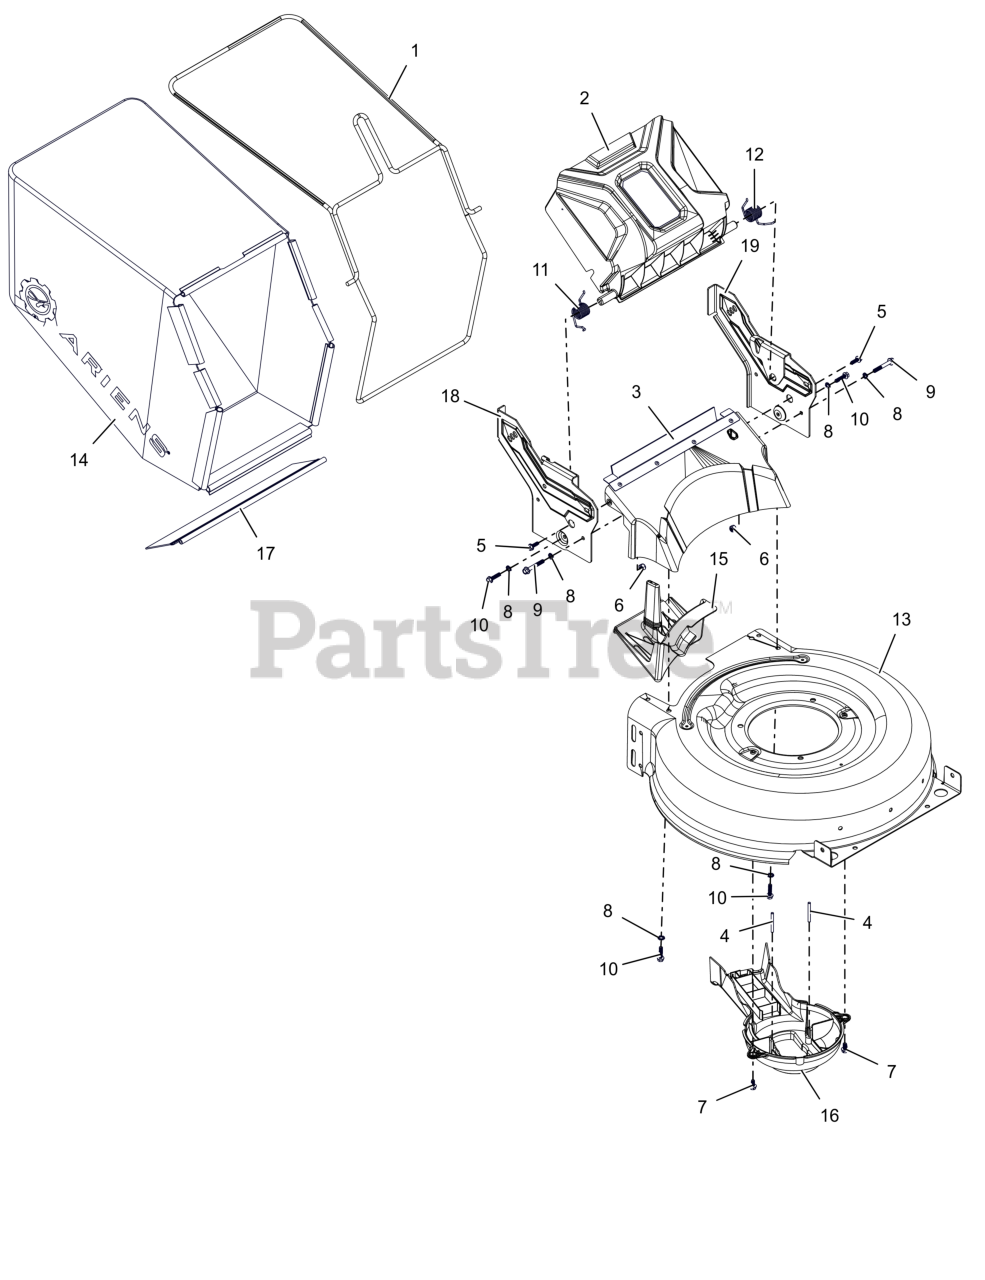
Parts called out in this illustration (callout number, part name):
1	WLDMT, BAG FRAME (ORANGE)
2	ASM, REAR DOOR
3	ASM, REAR COVER-RWD
4	PIN, .188 X 1.750
5	SCR, HI-LO HWH 1/4-15 X .750
6	NUT, NYLOC 1/4-20
7	SCR, 1/4-20X.500, THREAD FORMING
8	WSHR-LK-EXT, .256X.510X.028
9	BLT, HEX 1/4-20 X 1.75 GR5
10	SCR, HI-LO HWH 1/4-15 X 1.00
11	SPRG, TORSION - DOOR LH
12	SPRG, TORSION - DOOR RH
13	DECK, RWD -21 (ORANGE)
14	BAG, ARIENS
15	PLUG, MULCH
16	COVER, RWD PULLEY
17	GUARD, REAR DECK
18	BRKT, RH SIDE - RWD (BLACK)
19	BRKT, LH SIDE - RWD (BLACK)
